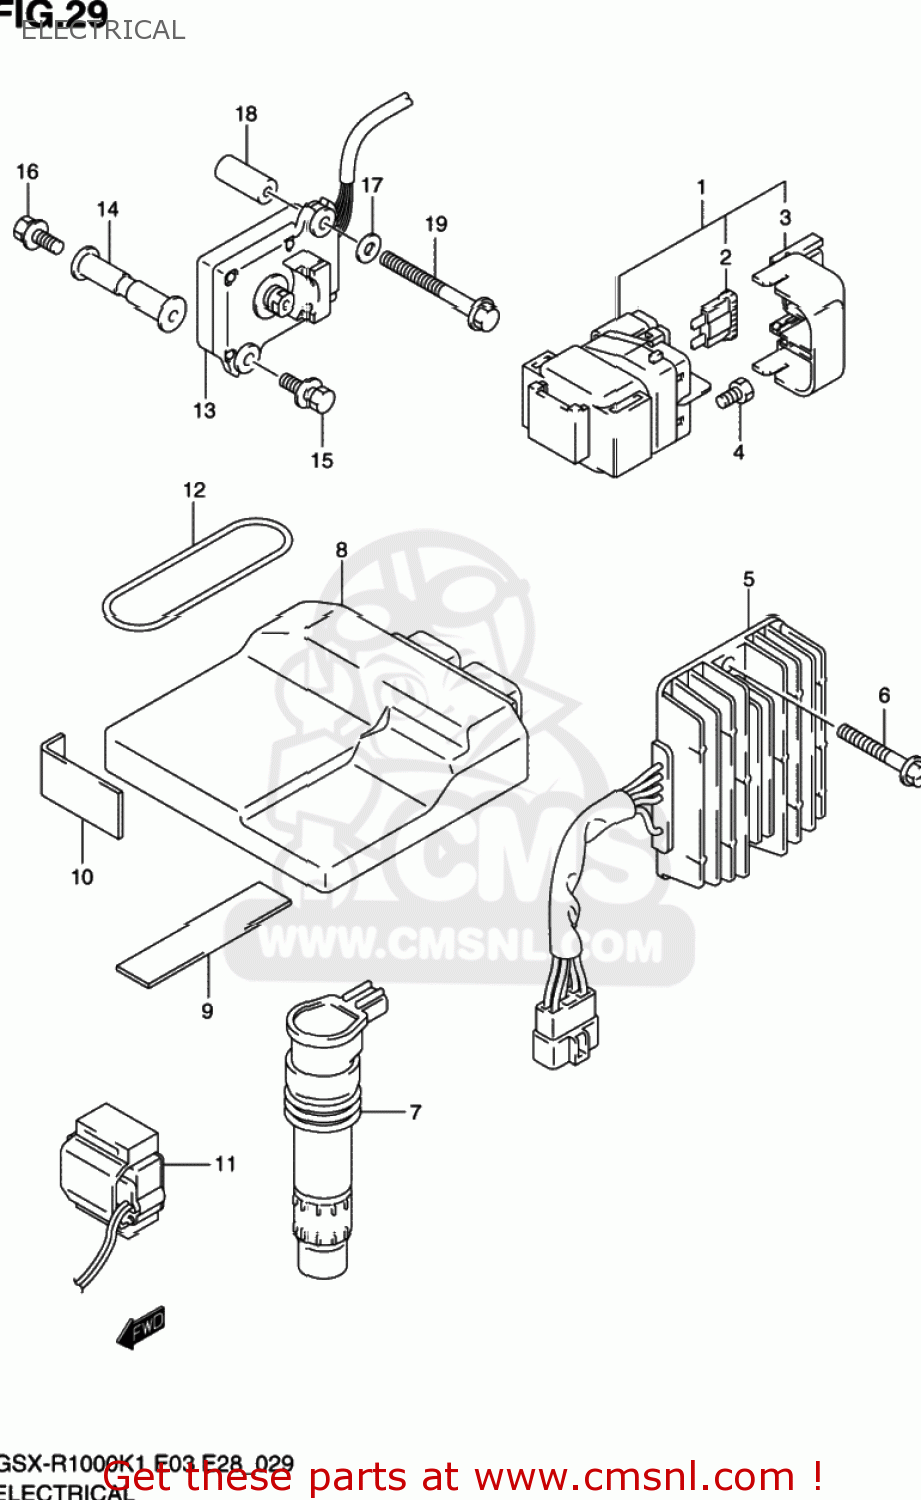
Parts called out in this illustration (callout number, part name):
1	RELAY ASSY,STARTING MOTOR
2	FUSE(30A)
3	COVER,STARTER RELAY
4	SCREW(6X8)
5	RECTIFIER ASY
6	BOLT
7	COIL ASSY,IGNITION
8	CONTROL UNIT,FI
9	PROTECTOR(80X80X2)
10	PROTECTOR(170X95X3.0)
11	SENSOR ASSY,FUEL CUT
12	O RING(D:3.53,ID:69.44)
13	ACTUATOR ASSY
14	SPACER,ACTUATOR
15	BOLT(6X25)
16	BOLT(6X16)
17	WASHER(6.5X18X1.6)
18	SPACER(6.2X15.5X35)
19	BOLT
